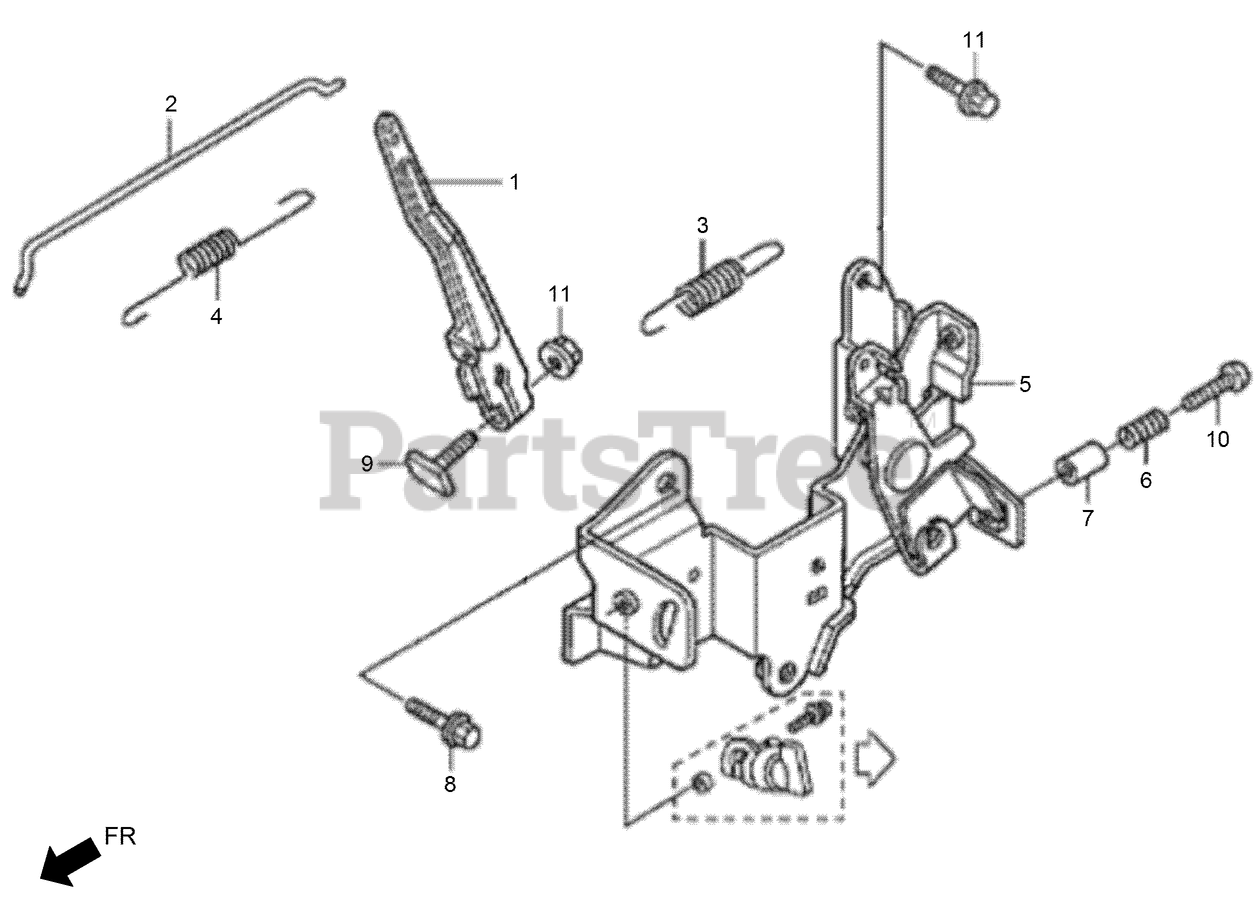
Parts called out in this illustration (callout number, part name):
1	ARM-GOVERNOR
2	ROD-GOVERNOR
3	SPRING-GOVERNOR
4	SPRING-THROTTLE RETURN
5	CONTROL BASE ASM
6	SPRING-CONTROL ADJUSTING
7	COLLAR-STOPPER
8	BOLT-FLANGE-5X12
9	BOLT-GOVERNOR ARM
10	SCREW-RECESSED-5X28
11	NUT-FLANGE-6MM
